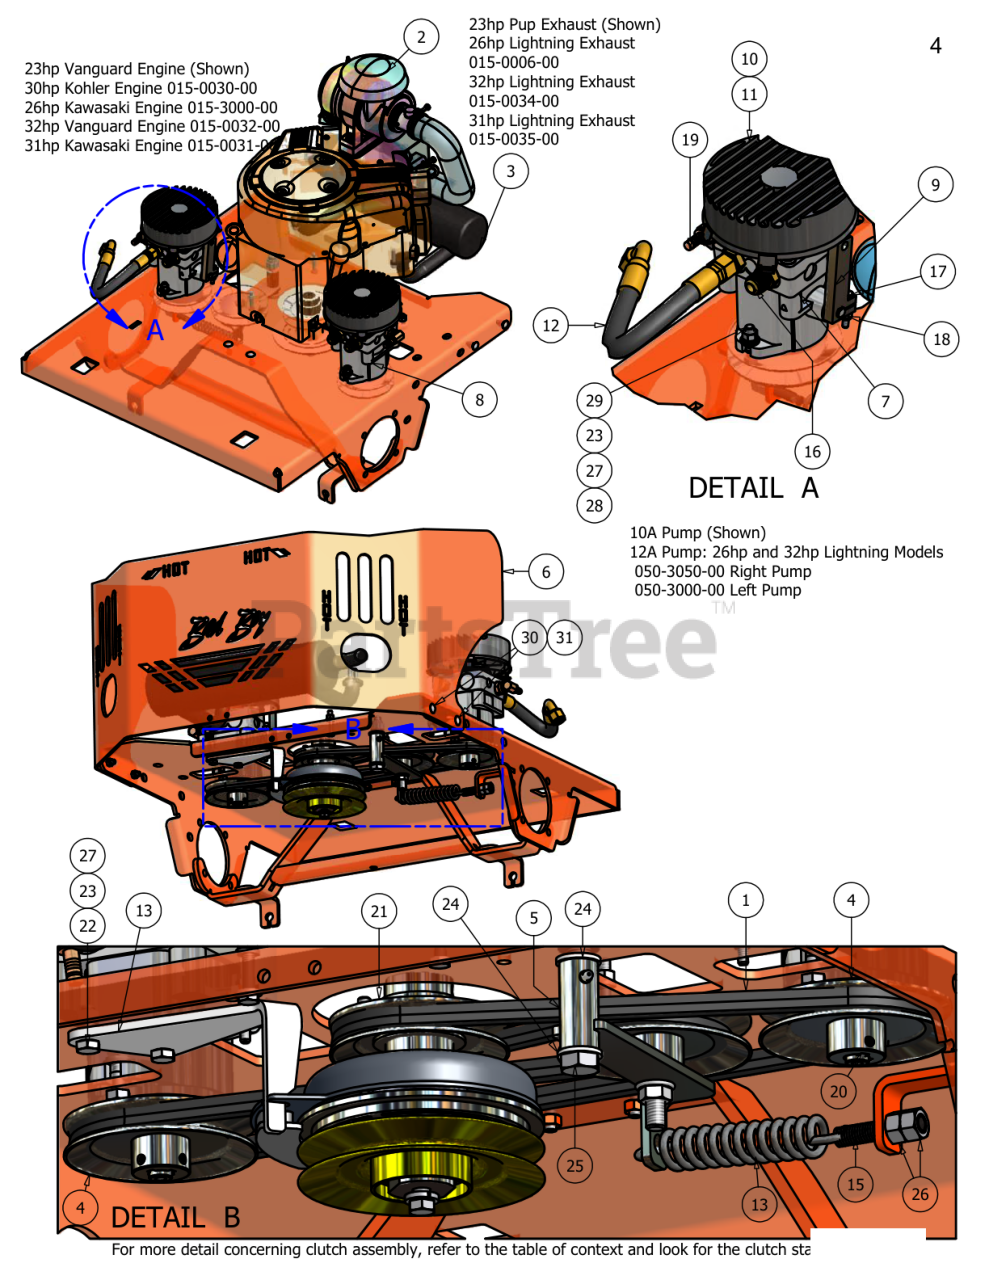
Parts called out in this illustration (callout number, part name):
2	23 HP Vanguard Motor
3	23 HP Vanguard Exhaust
4	5" Pump Pulley
5	Pump Idler Bracket
6	Pup Rear Plate
7	Right Hydraulic Pump
8	Left Hydraulic Pump
9	Pup Pump Arm
10	Hydraulic Fan
12	Hydraulic Hose
13	PTO Engager Holder
14	Pump Idler Spring 6"
15	Spring Tensioner
16	Hydraulic Fitting
17	1/4" x 1 1/2" Bolt
18	1/4" Nylock Nut
19	3/8" X 9/16" Male Fitting
20	5mm x 1" Key
21	4 3/4" Motor Pulley
22	3/8" x 1" Hex Bolt
23	3/8" Hex Nut
24	.635 ID Plastic Washer
25	5/8" x 4" Hex Bolt
26	1/2" Hex Nut
27	3/8" Lock Washer
28	3/8" Flat Washer
29	3/8" x 1 1/2" Hex Bolt
30	5/16" x 1" Carriage Bolt
31	5/16" Nylock Nut
32	Canister Filter (23 Pup only)
33	Outer Canister Air Filter (26hp & 32hp Lightning and 30hp Pup)
34	Inner Canister Air Filter (26hp & 32hp Lightning and 30hp Pup)
